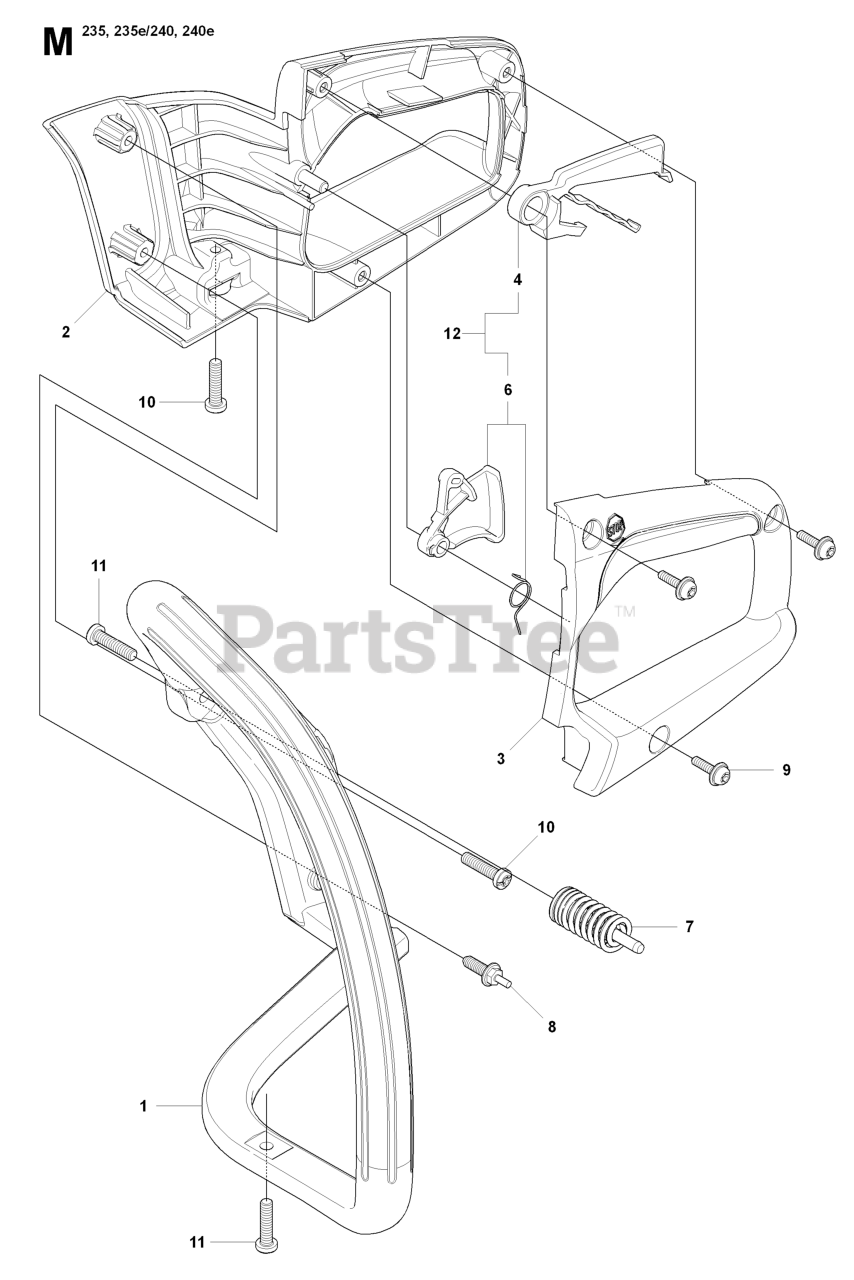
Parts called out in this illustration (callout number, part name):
1	FRONT HANDLE
2	REAR HANDLE
3	REAR HANDLE COVER
3	COVER REAR HANDLE
4	LOCKOUT - THROTTLE
6	TRIGGER & SPRING ASSY
7	SPRING CYLINDER ASSY
10	SCREW FILTER PLATE
11	SCREW M5.38-14X22.225MM
12	TRIGGER & LOCKOUT KIT
